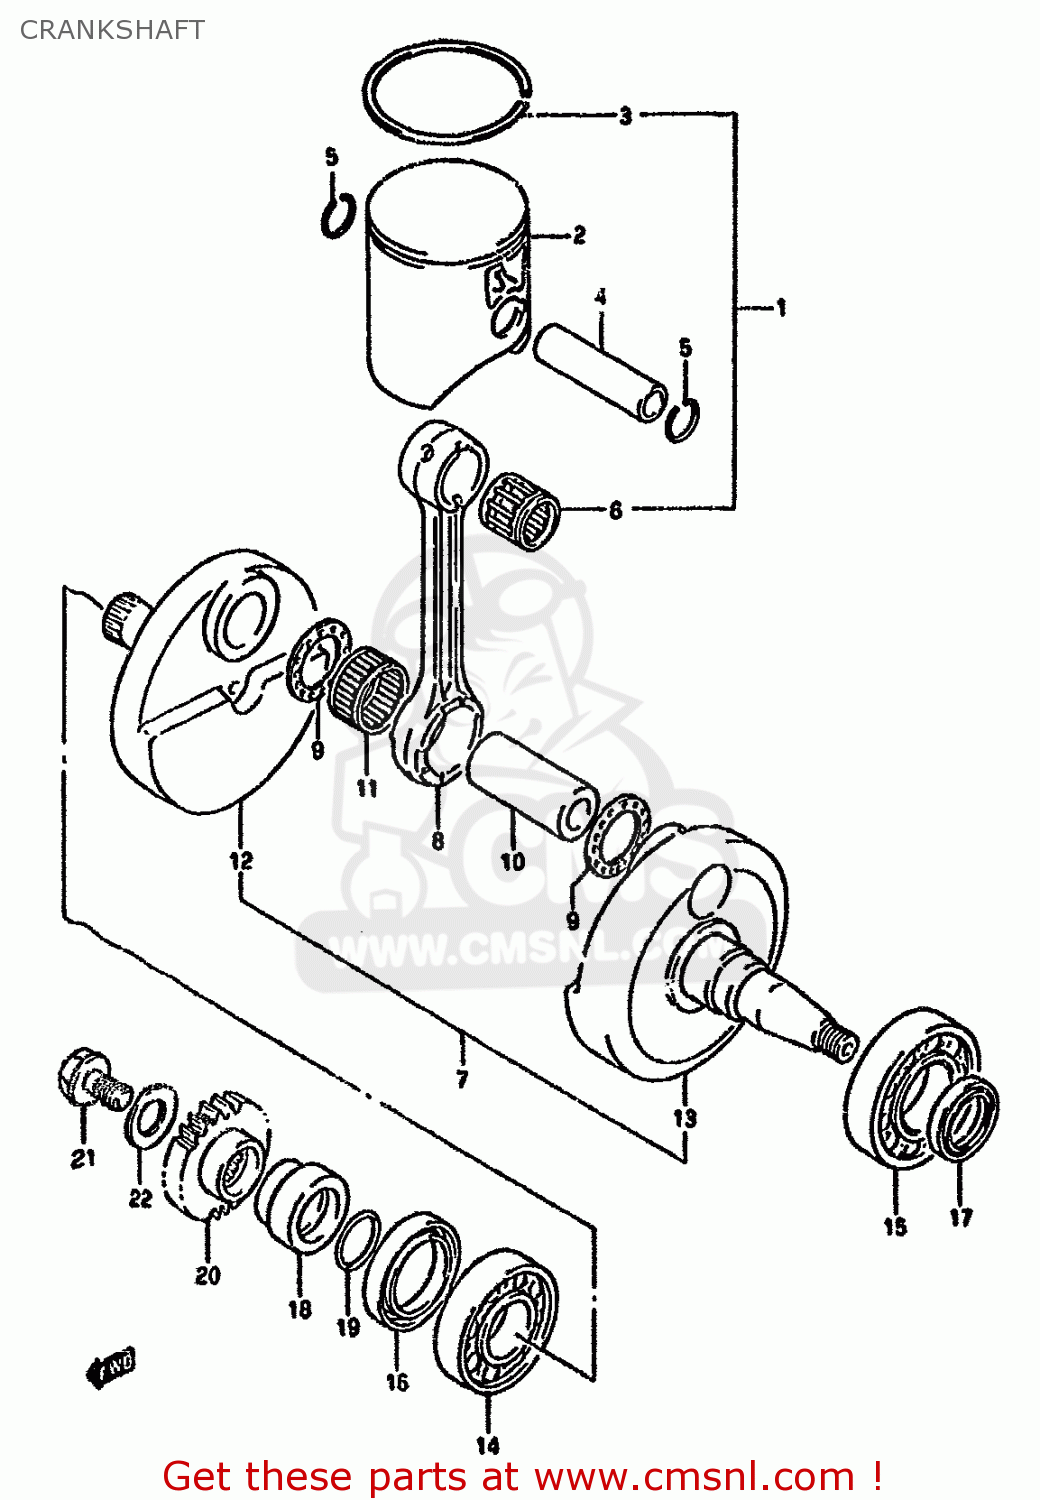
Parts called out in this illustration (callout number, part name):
1	PISTON KIT
2	PISTON
3	RING,PISTON
4	PIN,PISTON
5	CIRCLIP,PISTON PIN
6	BEARING(18X23X22)
7	CRANKSHAFT ASSEMBLY
8	ROD,CONNECTING
9	WASHER(24X38.5X1.5)
10	PIN,CRANK
11	BEARING(24X30X20)
12	CRANKSHAFT,R
13	CRANKSHAFT,LEFT
14	BEARING(25X62X17)
15	BEARING 28X68X18
16	SEAL,OIL(36X52X7)
17	SEAL,OIL(25X37X6)
18	SPACER,PRIMARY DRIVE GEAR
19	O RING(D:2.4,ID:21.8)
20	GEAR,PRIMARY DRIVE (NT:
21	BOLT,PRIMARY DRIVE GEAR
22	WASHER
